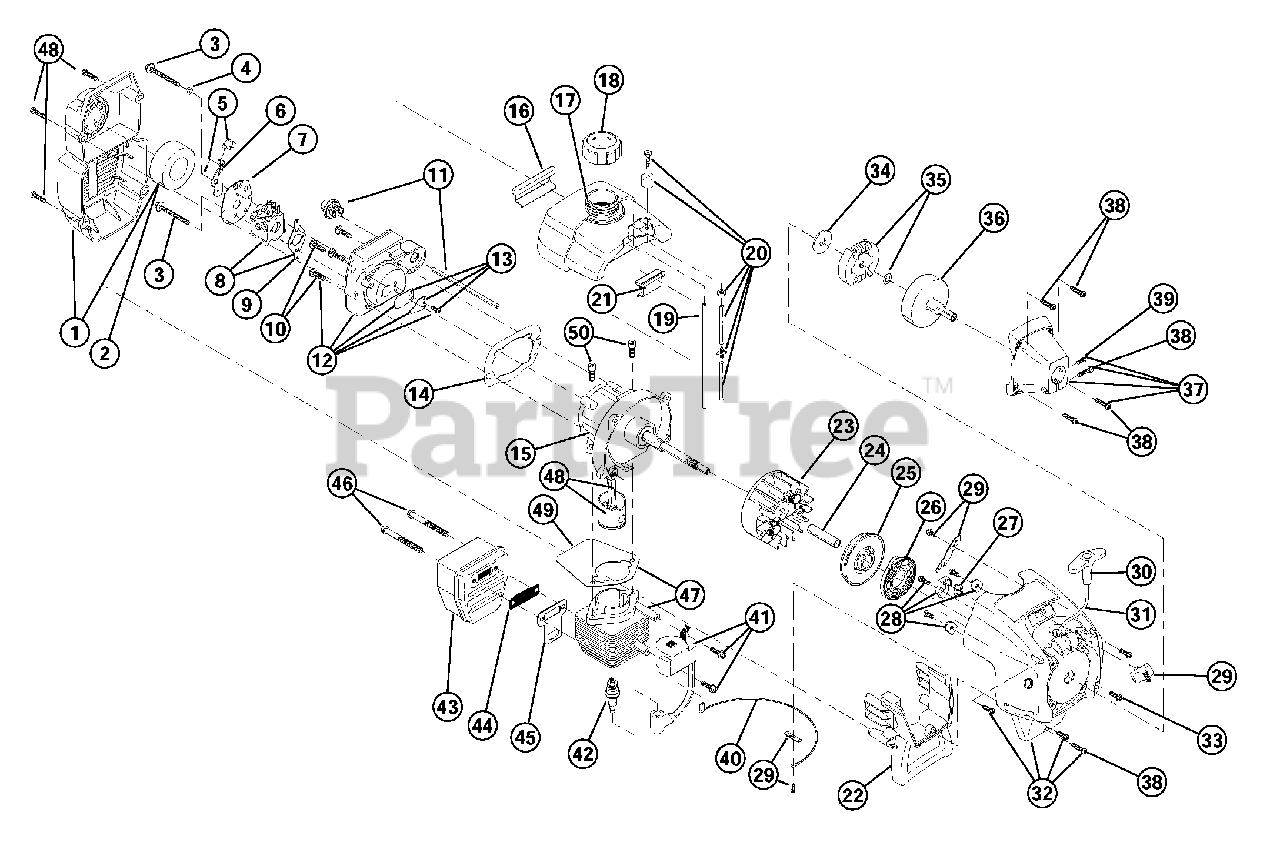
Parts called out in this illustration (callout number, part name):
1	Air Cleaner/Muffler Cover Assembly
2	Air Cleaner Filter
3	Carburetor Mounting Screw Assembly
4	Wavey Washer
5	Choke Knob and Screw
6	Choke Lever Assembly
7	Choke Lever and Plate
8	Carburetor Assembly
9	Carburetor Gasket
10	Carb Mount Screw
11	Primer and Hose Assembly
12	Carb Mount Assembly
13	Reed Assembly
14	Carburetor Mount Gasket
15	Crank Case Service Assembly
16	Rear Mounting Pad
17	Fuel Tank Assembly
18	Fuel Cap Assembly
19	Fuel Return Line
20	Fuel Line Assembly
21	Front Mounting Pad
22	Shroud Extension and Stand
23	Flywheel Assembly
25	Recoil Pulley Assembly
26	Recoil Spring
27	Rope Guide
28	Pulley Retainer Assembly
29	Switch Assembly
30	Pull Handle
32	Starter Housing Assembly
33	Housing Screw
34	Clutch Washer
35	Clutch Rotor Assembly
36	Clutch Drum Assembly
37	Clutch Cover Assembly
39	Anti-Rotation Screw
40	Wire Lead
41	Module Assembly
42	Spark Plug
43	Muffler Assembly
44	Spark Arrestor Screen
45	Exhaust Gasket
46	Muffler Mounting Bolt Assembly
47	Cylinder Assembly
48	Piston and Rod Assembly
49	Cylinder Gasket
50	Cylinder Bolt
